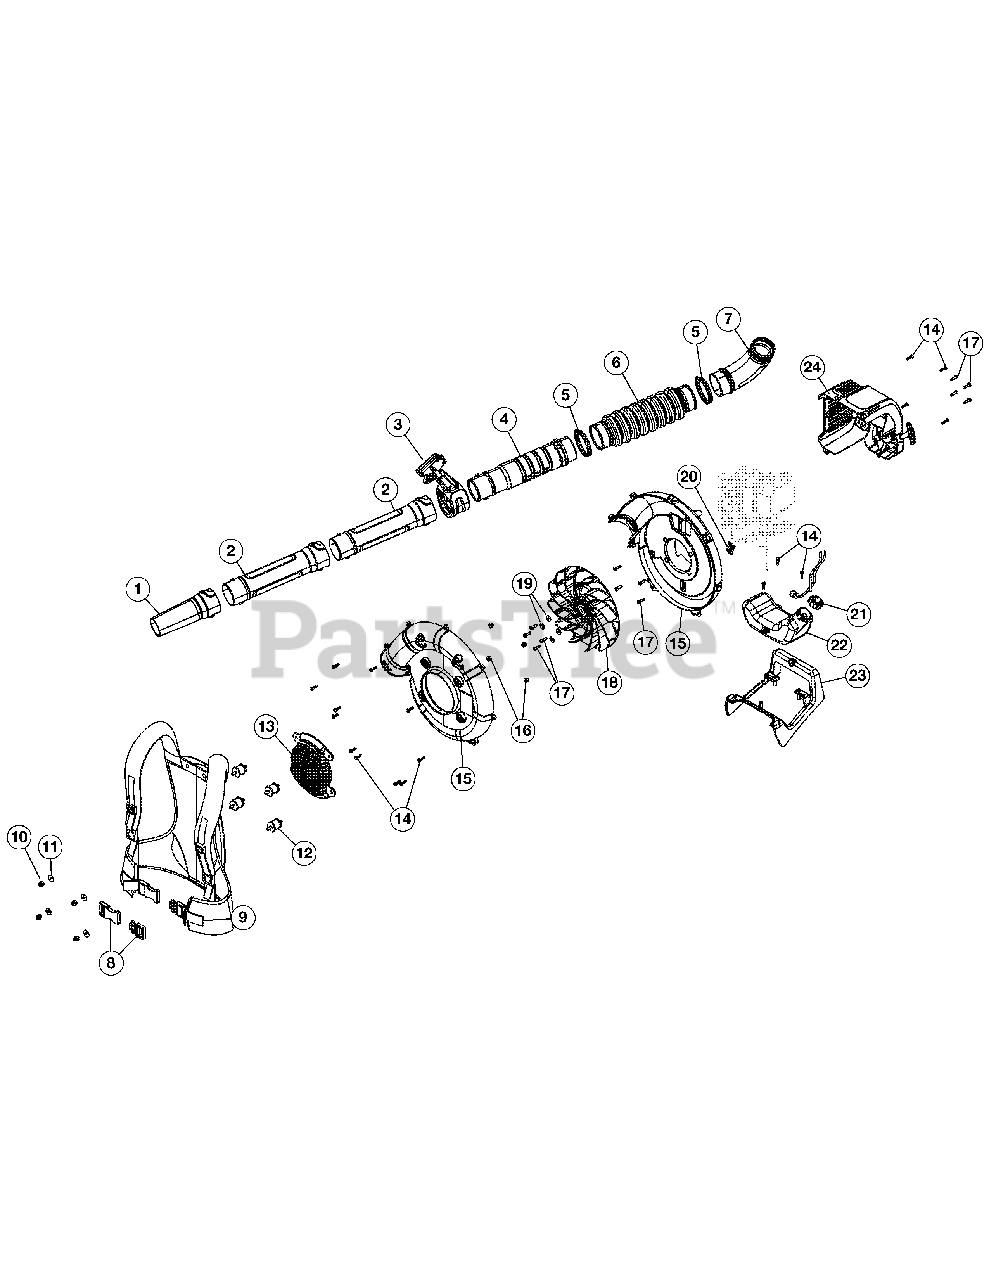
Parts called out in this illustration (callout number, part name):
1	Nozzle
2	Lower Blower Tube
3	Throttle Grip Assembly
4	Upper Blower Tube
5	Clamp
6	Flex Tube
7	Elbow Tube
8	Harness Clip
9	Harness
10	Nut
11	Spacer
12	Insulator Mount
13	Intake Cover
14	Screw
15	Impeller Housing Assembly
16	Nut
17	Screw
18	Impeller
20	Throttle Retaining Clip
21	Fuel Cap
22	Fuel Tank Assembly
24	Engine Cover Assembly
